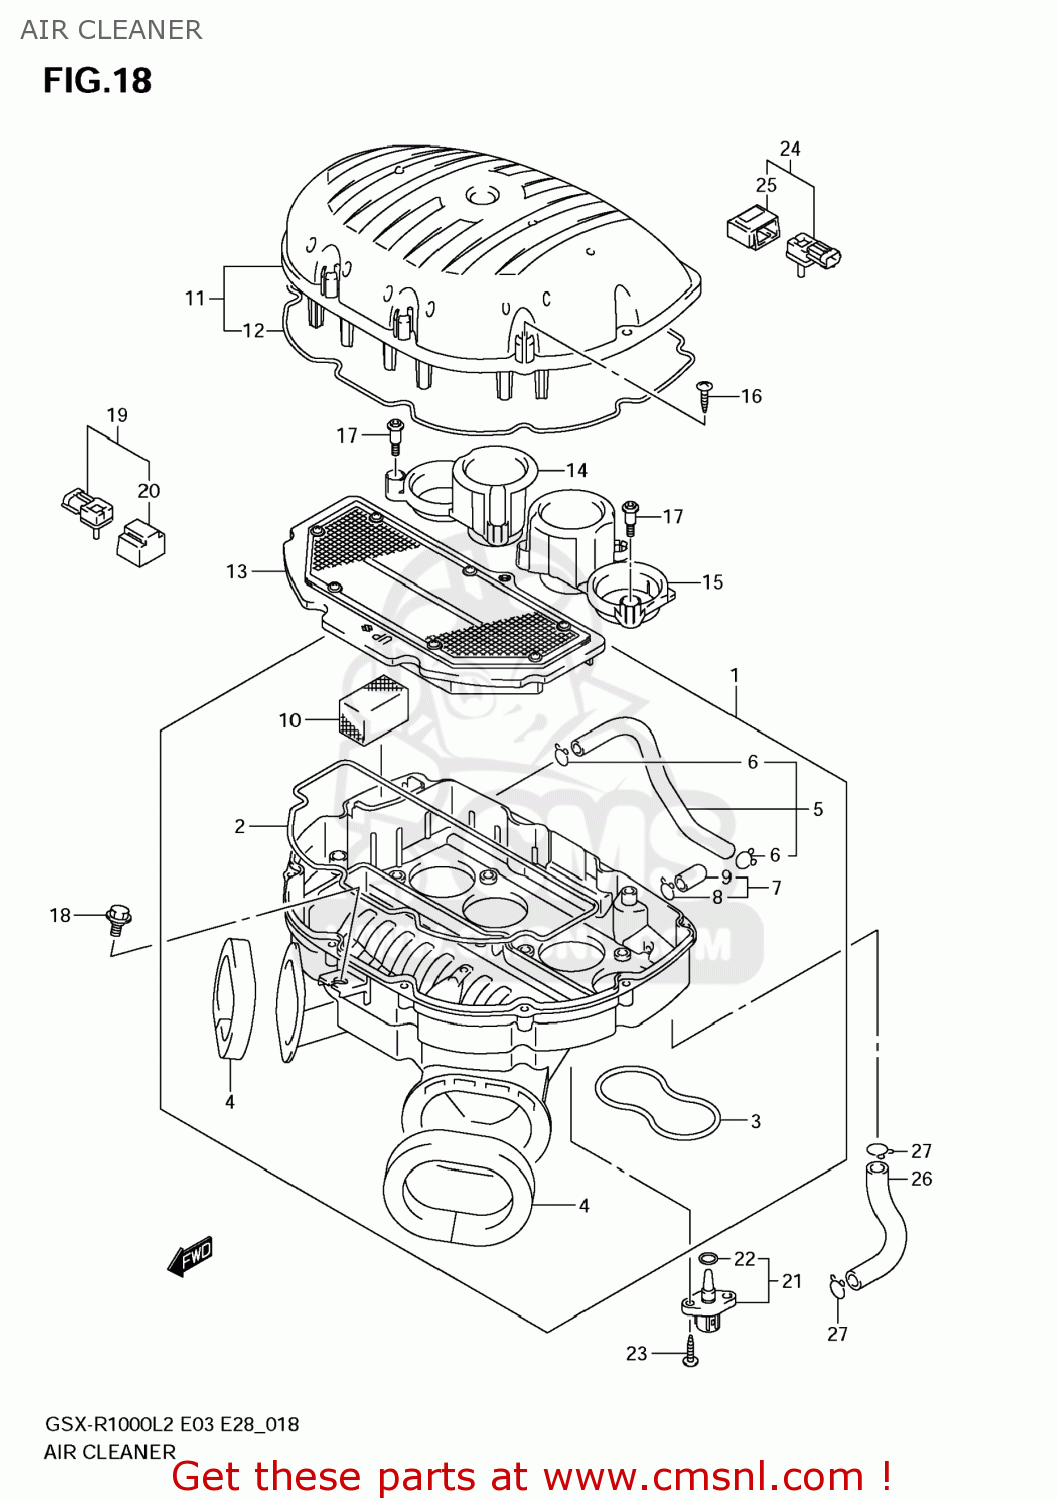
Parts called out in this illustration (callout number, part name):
1	CASE,AIR CLEAN
2	GASKET,CASE (NAS)
3	GASKET,CASE (NAS)
4	CUSHION,DUCT
5	TUBE,BREATHER
6	CLIP
7	PLUG ASSY,DRAIN
8	CLIP
9	PLUG
10	FILTER,BREATHER
11	CAP,AIR CLEANER
12	GASKET,CAP (NAS)
13	FILTER ASSY
14	FUNNEL,OUTLET,R
15	FUNNEL,OUTLET,L
16	SCREW
17	BOLT,AIR CLEANER CASE
18	BOLT(6X16)
19	SENSOR,BOOST
20	COVER
21	SENSOR,AIR TEM
22	O RING
23	SCREW
24	SENSOR,AIR PRESSURE
25	COVER
26	HOSE,ISC VALVE
27	CLIP
